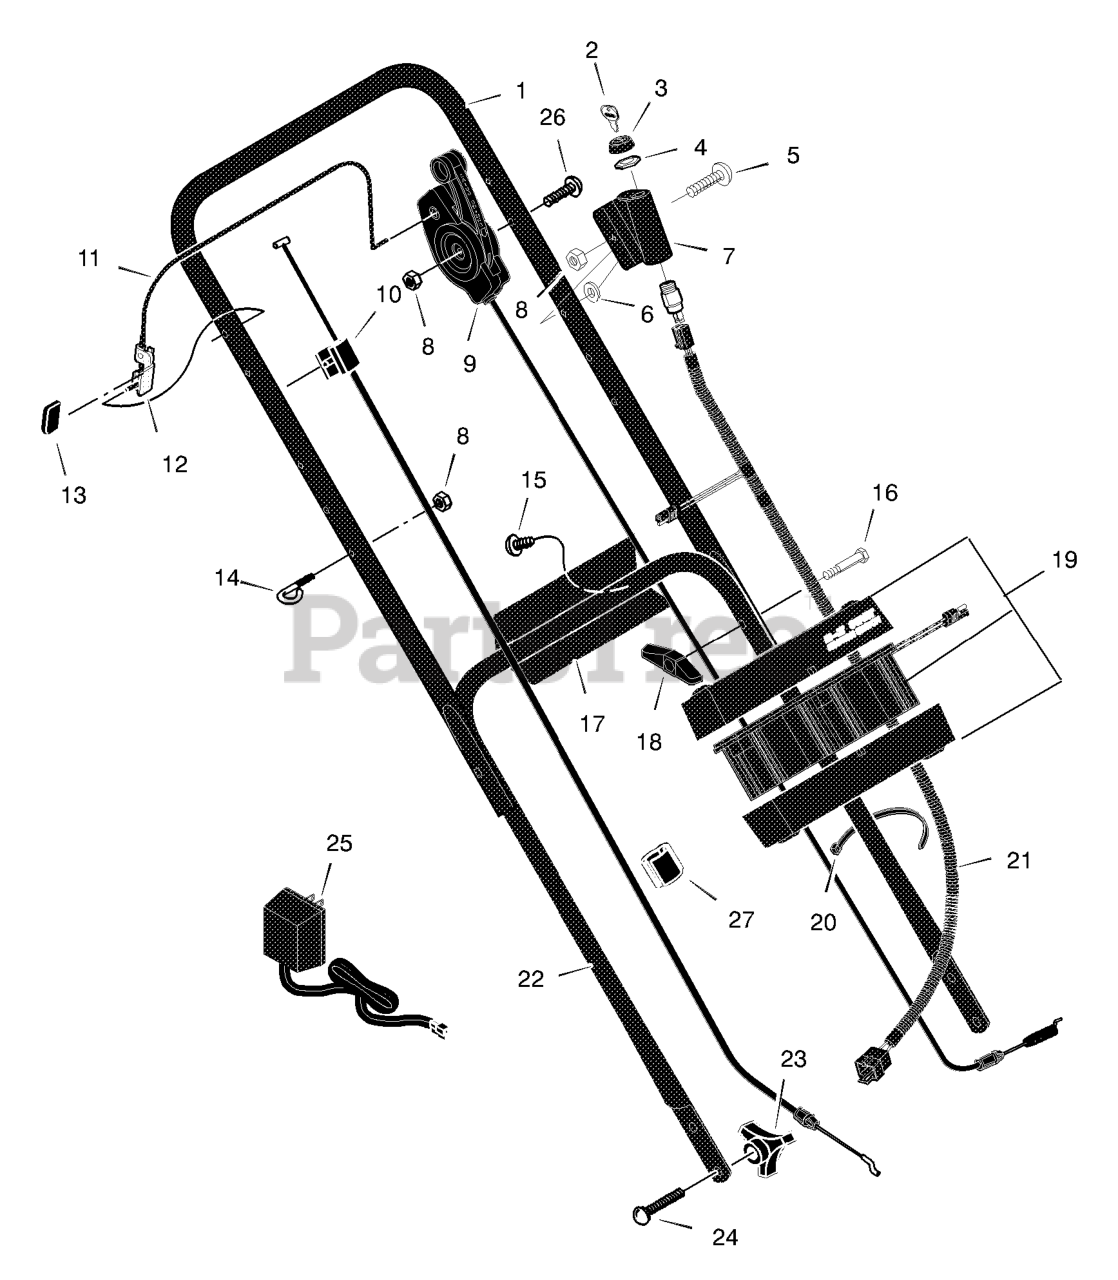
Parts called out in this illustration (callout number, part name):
1	Handle, Upper
2	Key and Ring
3	Cap, Ignition Switch
4	Nut, Ignition Switch
5	Bolt, Hex
7	Case, Ignition Switch
8	Nut, Nylock
9	Cable Assembly, Drive
10	Cable, Engine Stop
11	Lever, Engine Stop
12	Bracket, Stop Lever
13	Sleeve, Vinyl
14	Guide, Rope
16	Bolt, Carriage
17	Bracket, Battery
18	Wingnut
19	Battery Assembly
20	Strap, Tie
21	Harness Assembly, Wiring
22	Handle, Lower
24	Bolt, Carriage
25	Charger, Battery
26	Bolt, Hex
27	Fastener, Cable
